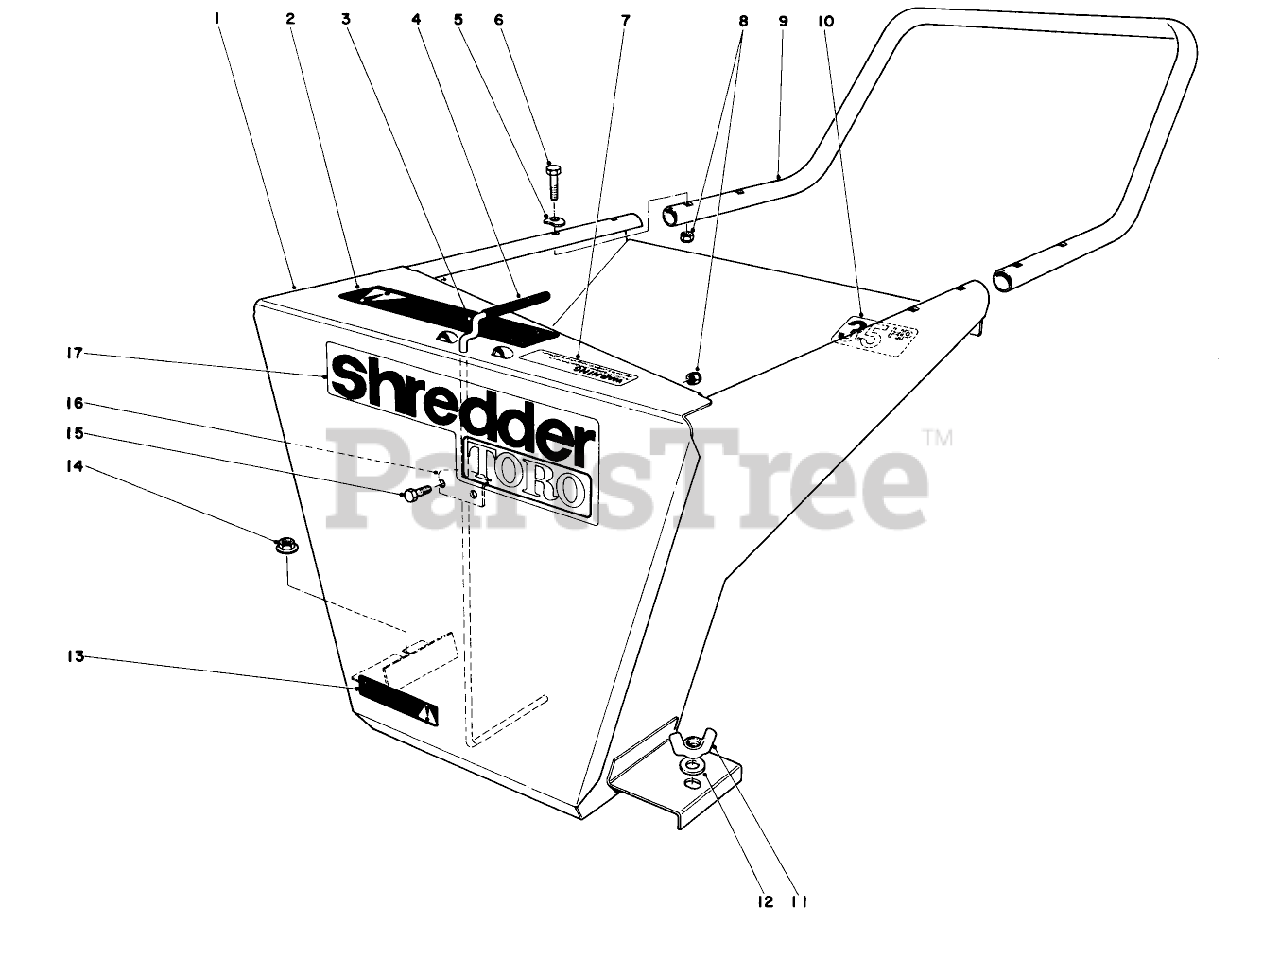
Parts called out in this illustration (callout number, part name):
1	Hopper
2	Caution Decal
3	Feeder Rod w/Grip
4	Handle Grip
5	Bent Washer
6	SCREW-HH
7	Warning Decal
8	NUT-LOCK, CONE
9	Handle
10	Decal
11	Wing Nut
12	WASHER-FLAT
13	Decal-warning
14	Flange Locknut
15	SCREW-HH
16	Feeder Rod Bracket
17	Logo Decal
